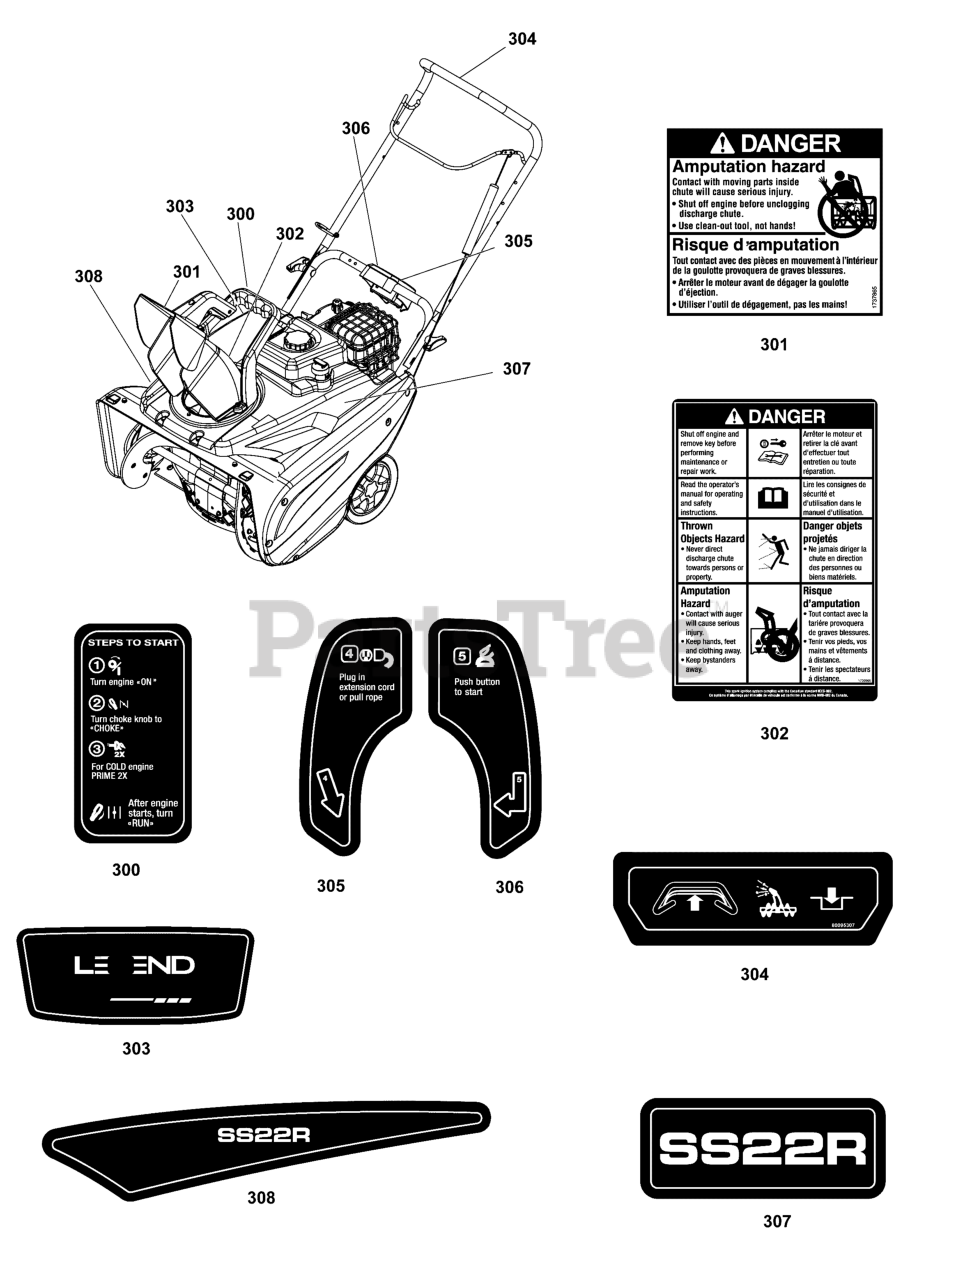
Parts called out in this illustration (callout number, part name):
300	DECAL, Step 1-2-3
301	DECAL, Danger Chute Warning, FR/ENG
302	DECAL, Chute, FR-EN
303	DECAL, Legend Force
304	DECAL, Bail Engagement
305	DECAL, 4, Start
306	DECAL, 5, Start
307	DECAL, Model
308	DECAL, SS22R
